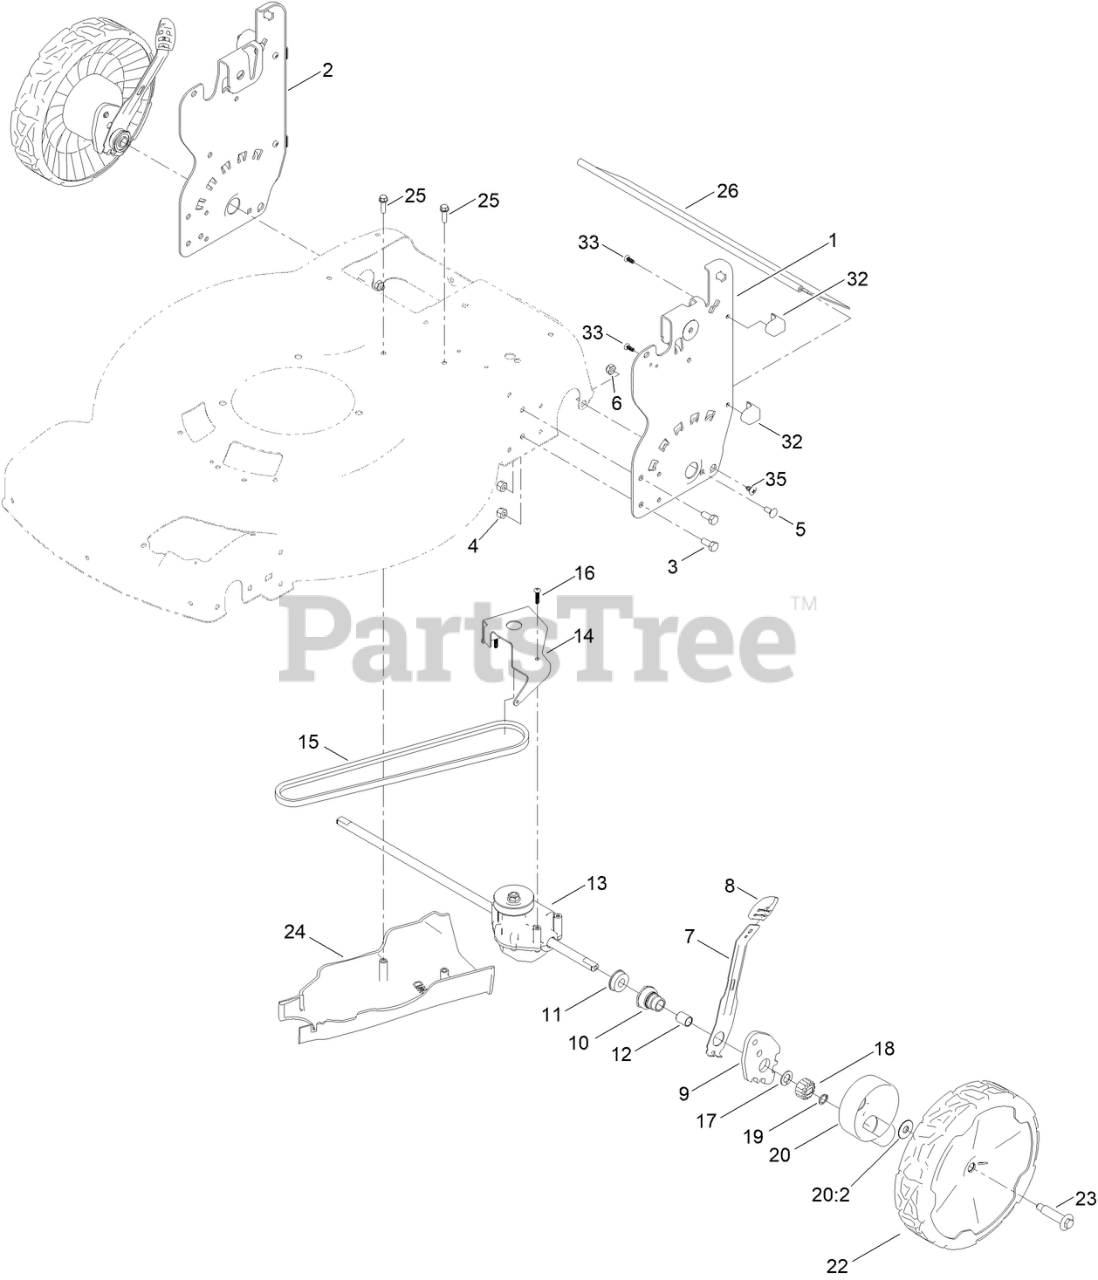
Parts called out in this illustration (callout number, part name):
1	PLATE-HOC, LH
2	PLATE-HOC, RH (2 HOLE)
3	SCREW-HH
4	NUT-LOCK, NI
5	SCREW-CARR
6	NUT-LOCK, NI
7	ARM-SPRING
8	KNOB-LEVER, HOC
9	ARM-PIVOT, REAR
10	RETAINER-BUSHING, HOC
11	BEARING-BALL
12	BUSHING-SLEEVE
13	TRANSMISSION-RWD
14	BRACKET-TRANSMISSION
15	V-BELT
16	SCREW-PLASTITE
17	WASHER-THRUST
18	GEAR-PINION, 15T
19	RING-RETAINING
20	ASM-COVER, GEAR (DK GRAY)
20:2	WASHER-STEPPED
22	ASM-9.65" WHEEL, GEARED
23	WHEEL BOLT
24	COVER-BELT, RWD
25	SCREW-HWH
26	SHIELD-TRAILING
32	PAD-SMART STOW
33	SCREW-PLASTITE
35	SCREW-THD
